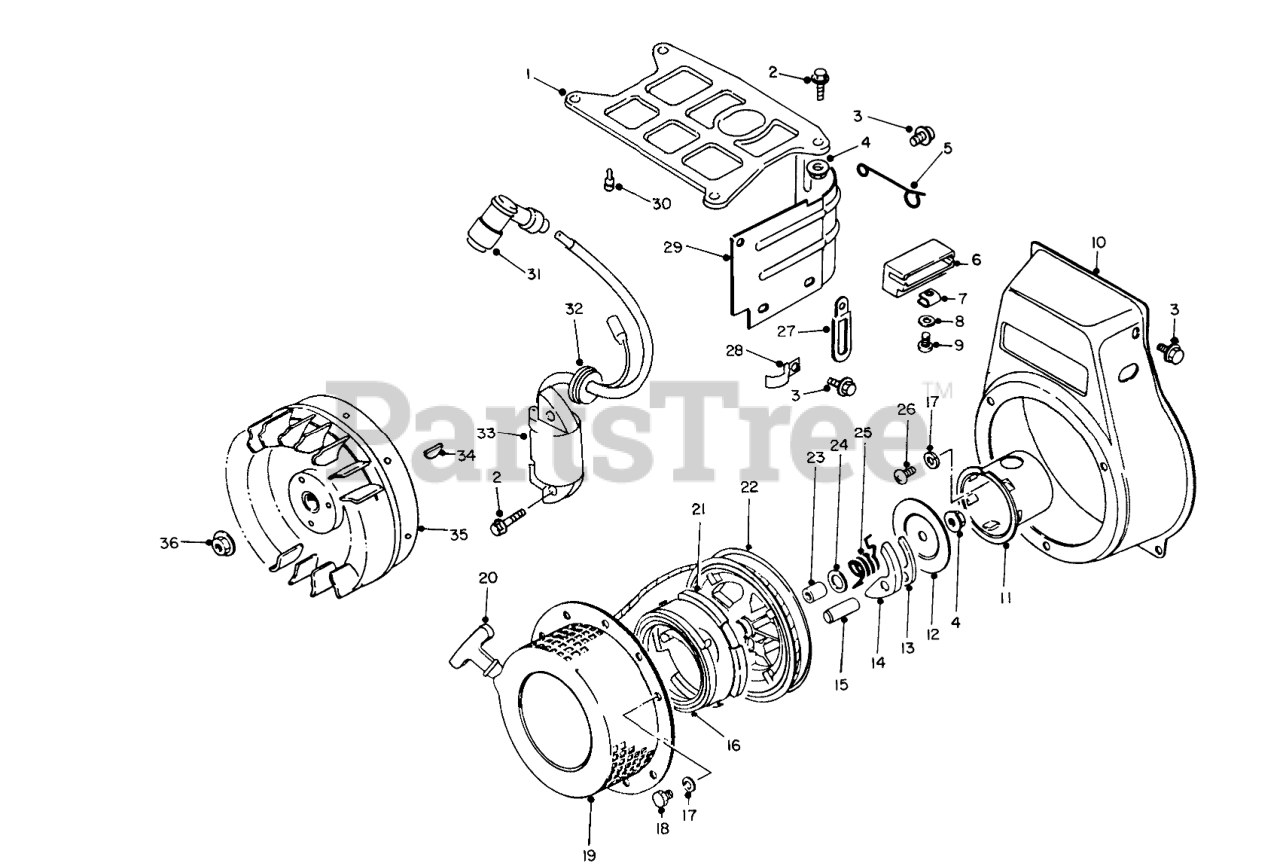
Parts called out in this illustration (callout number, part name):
1	Cowling-Upper
5	CLAMP
6	Holder-Lead Connector
8	Washer
10	COVER
11	Pulley-Starter
12	Plate
13	Ratchet
14	Ratchet
16	SPRING
17	LOCKWASHER
19	Starter Assembly (Incl. Ref. #4, 12-18 & 20-25)
20	Grip Assembly
21	SPRING CASE
23	Cover
24	Plate-Slide
25	Spring
26	Screw
27	CLAMP
28	Clamp
29	COWLING
30	Cushion
31	SPARK PLUG CAP
32	Grommet
33	STATOR
35	ROTOR ASM
